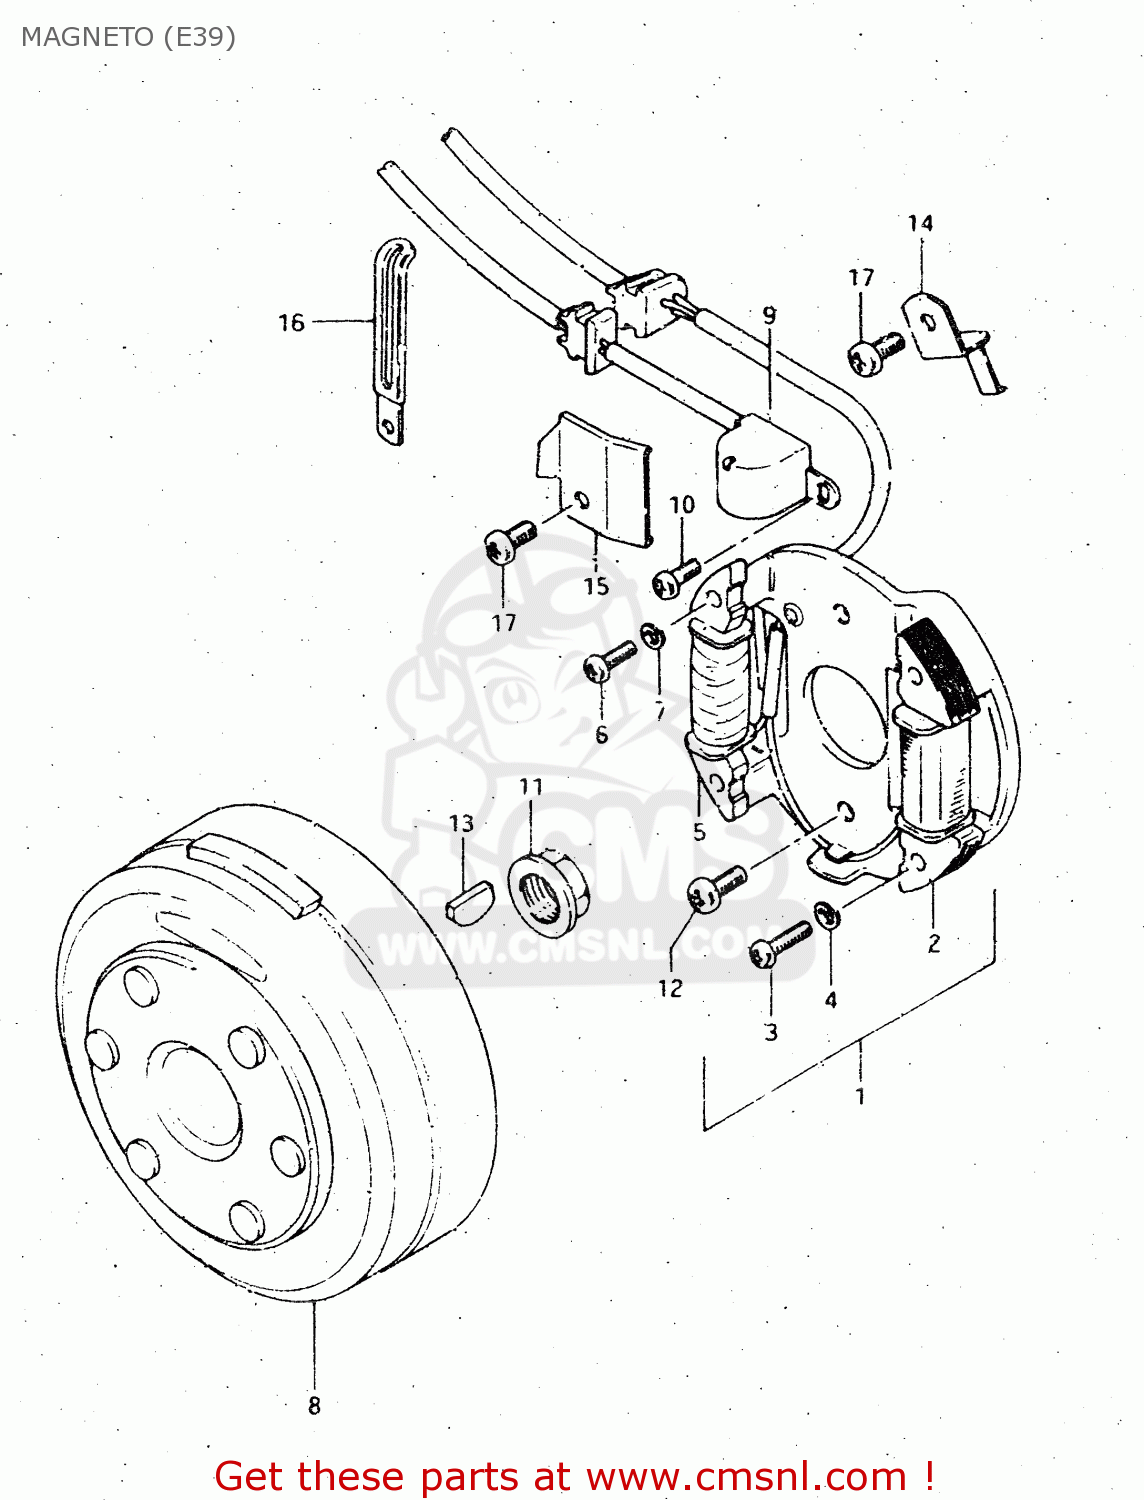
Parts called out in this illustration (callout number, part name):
1	STATOR ASSY
2	COIL,LIGHTING
3	SCREW
4	LOCK WASHER
5	COIL,PRIMARY
6	SCREW
7	LOCK WASHER
8	ROTOR,FLYWHEEL
9	COIL ASSY,PICK UP
10	SCREW (SUS)
11	NUT,GENERATOR ROTOR
12	SCREW
13	KEY 4MM
14	CLAMP,MAGNETO LEAD WIRE
15	CLAMP,MAGNETO LEAD WIRE
16	CLAMP
17	SCREW
